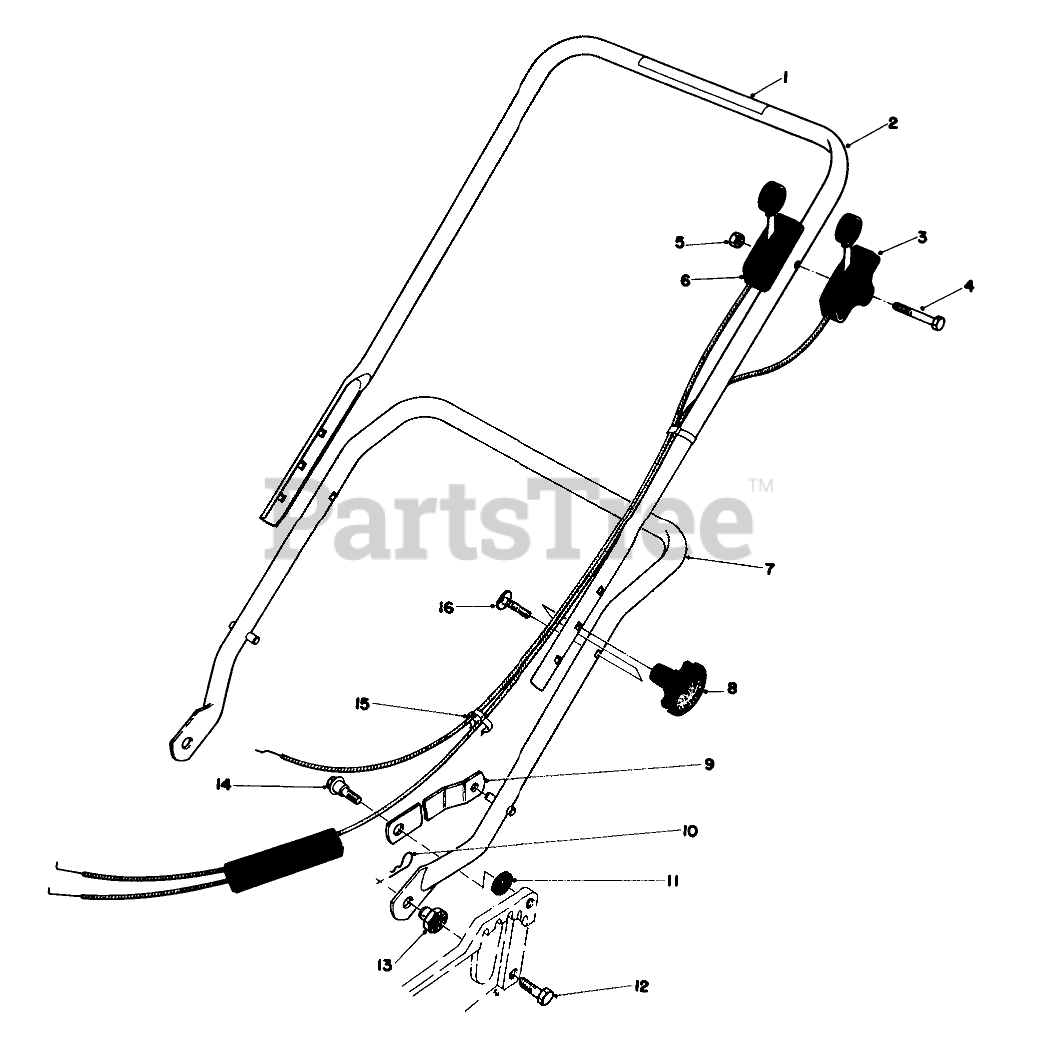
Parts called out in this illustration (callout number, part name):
1	Danger-Decal
2	Upper Handle
3	Traction Control
4	SCREW-HH
5	NUT-LOCK
6	Throttle Control
7	LOWER HANDLE ASM
9	HANDLE LATCH
10	PIN-COTTER, HAIR
11	SPACER
12	SCREW-HH
13	HANDLE PIVOT NUT
14	SCREW-SHOULDER
15	BOWDEN CLIP
16	SCREW-HANDLE
